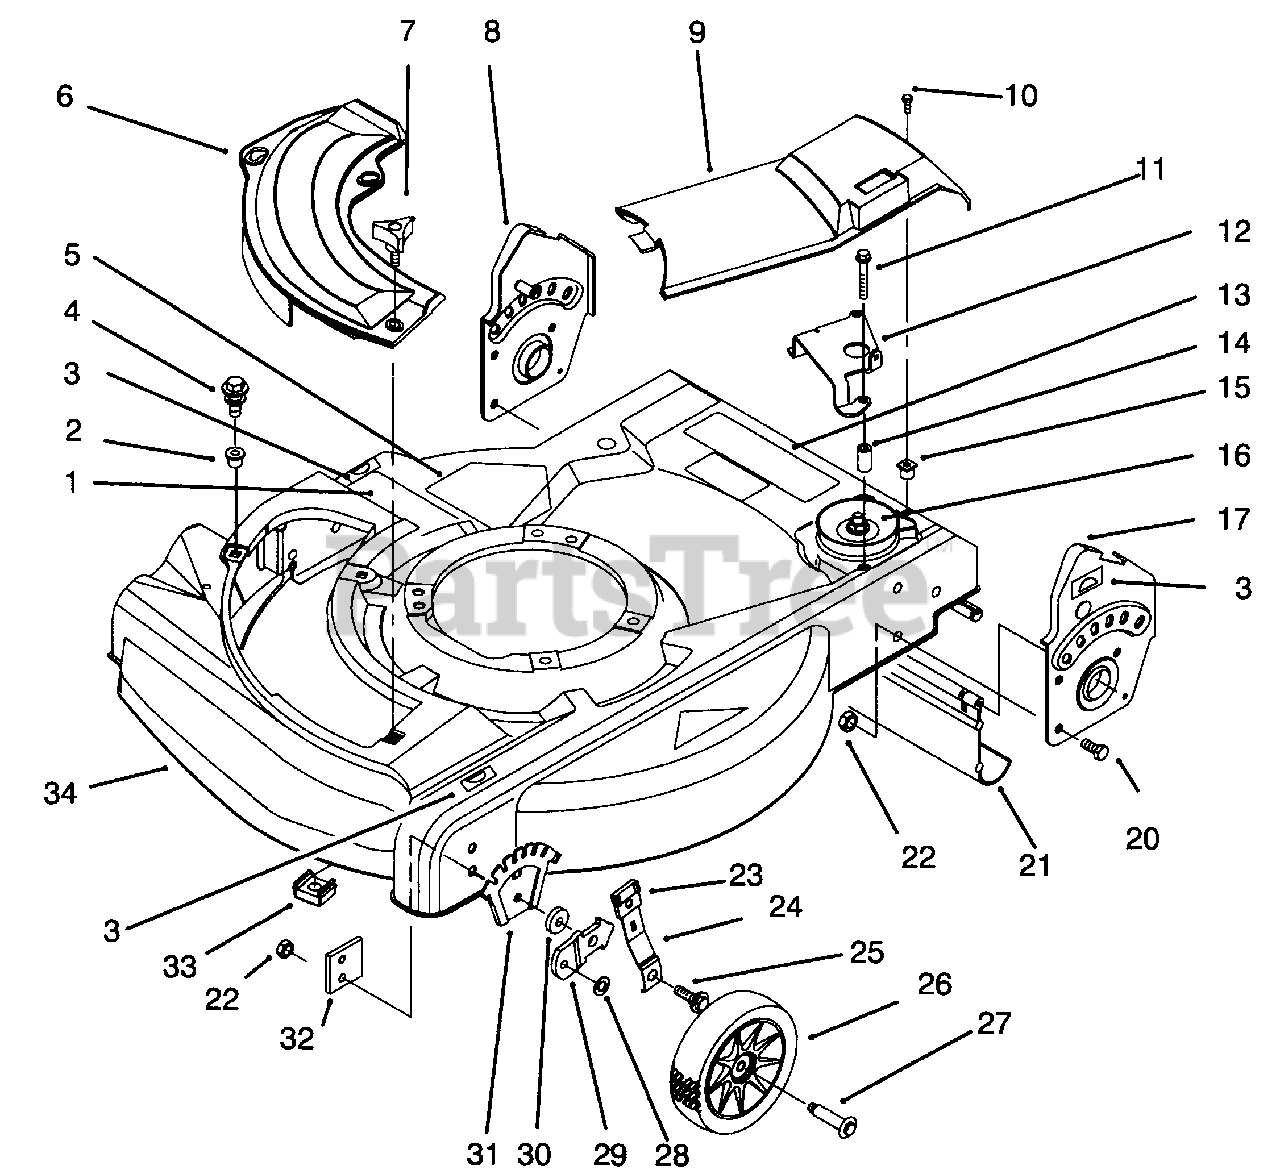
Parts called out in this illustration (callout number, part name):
1	Decal-Danger
2	Grommet-Plastic
3	Decal-H.O.C. L.H.
4	Screw-Thread Forming
5	Decal-Danger
6	Plate-Cover, Mulch
7	Knob
8	Handle Bracket Ass'y-R.H.
9	Cover-Drive
10	Screw
11	Screw-Thread Forming
12	Guide-Transmission
13	Decal-Warning
15	Grommet-Shroud Mtg.
16	Gear Case Ass'y
17	Handle Bracket Ass'y-L.H.
20	Screw-Hex. Hd.
21	Shield-Trailing
23	Knob-H.O.C.
24	Arm-Spring
25	Bolt-Shoulder
26	Wheel Assembly-6"
27	Bolt-Wheel
29	Bracket-H.O.C.
31	Plate H.O.C.
32	Plate-Baffle
33	Nut-Cage
34	Housing & Baffle Ass'y (Incl. Ref. # 1-5, & 13)
